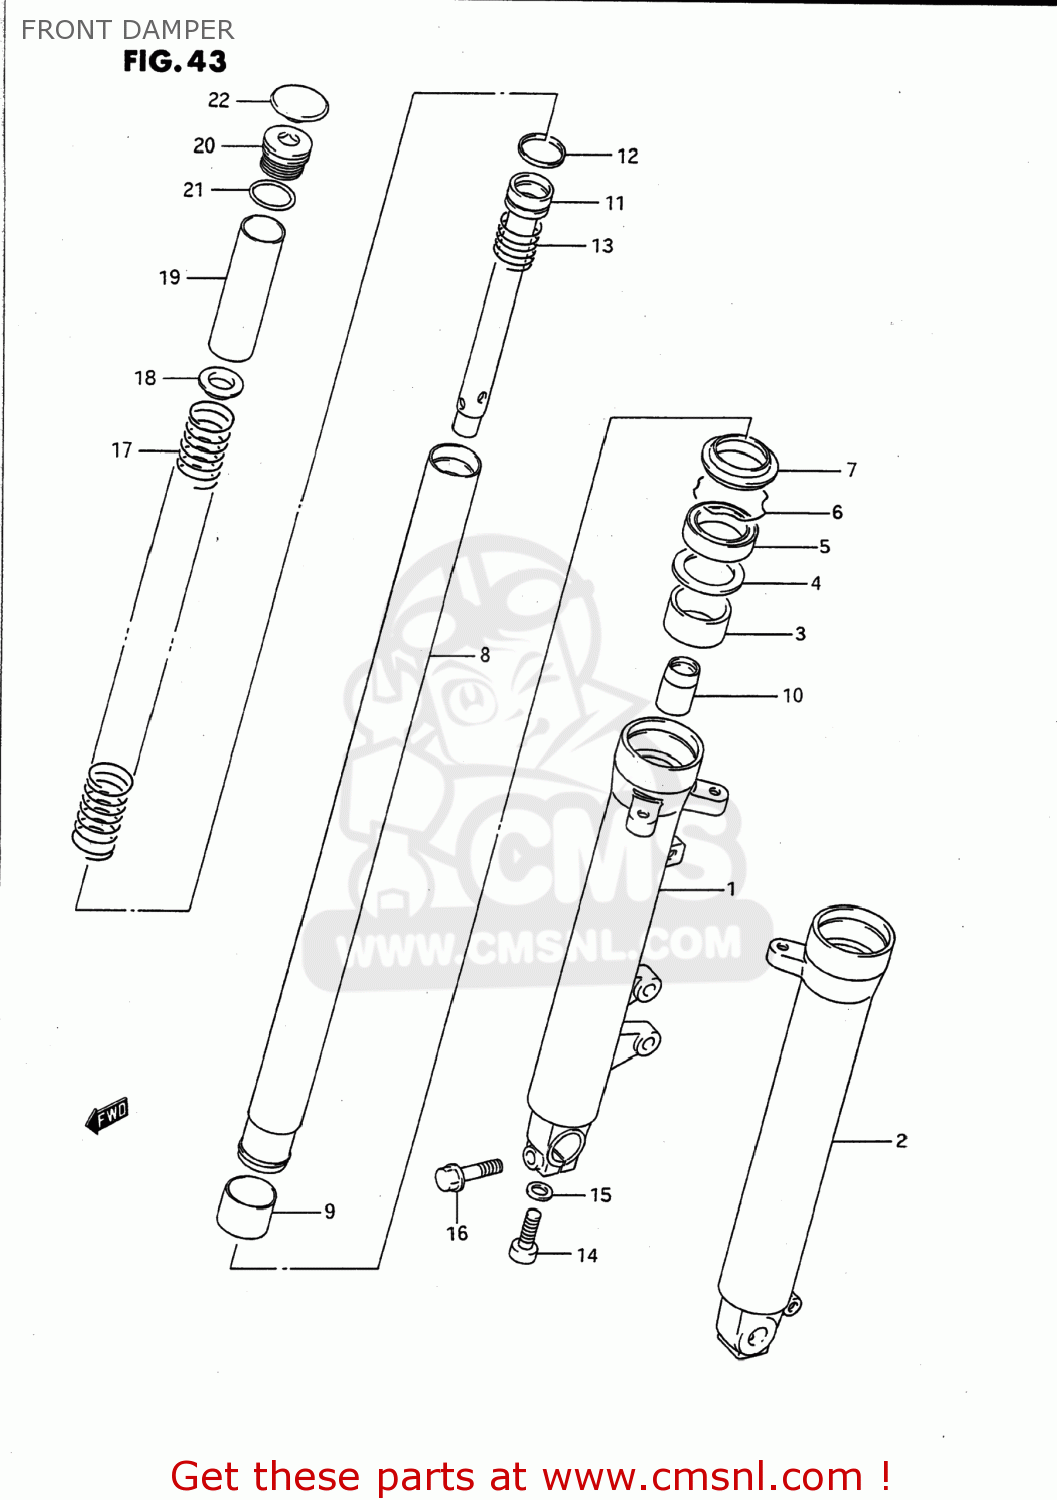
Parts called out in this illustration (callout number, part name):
1	TUBE,OUTER,RIGHT
2	TUBE,OUTER,LEFT
3	METAL,SLIDE
4	WASHER
5	OIL SEAL,FRONT FORK
6	RING,STOPPER
7	DUST SEAL,FRONT FORK
8	TUBE,INNER
9	PISTON
10	PIECE,OIL LOCK
11	CYLINDER
12	RING,PISTON
13	SPRING,REBOUND
14	BOLT,FORK CYLINDER(10X25)
15	GASKET (NAS)
16	BOLT
17	SPRING
18	GUIDE
19	SPACER
20	BOLT,FORK
21	O RING
22	CAP,FR FORK
